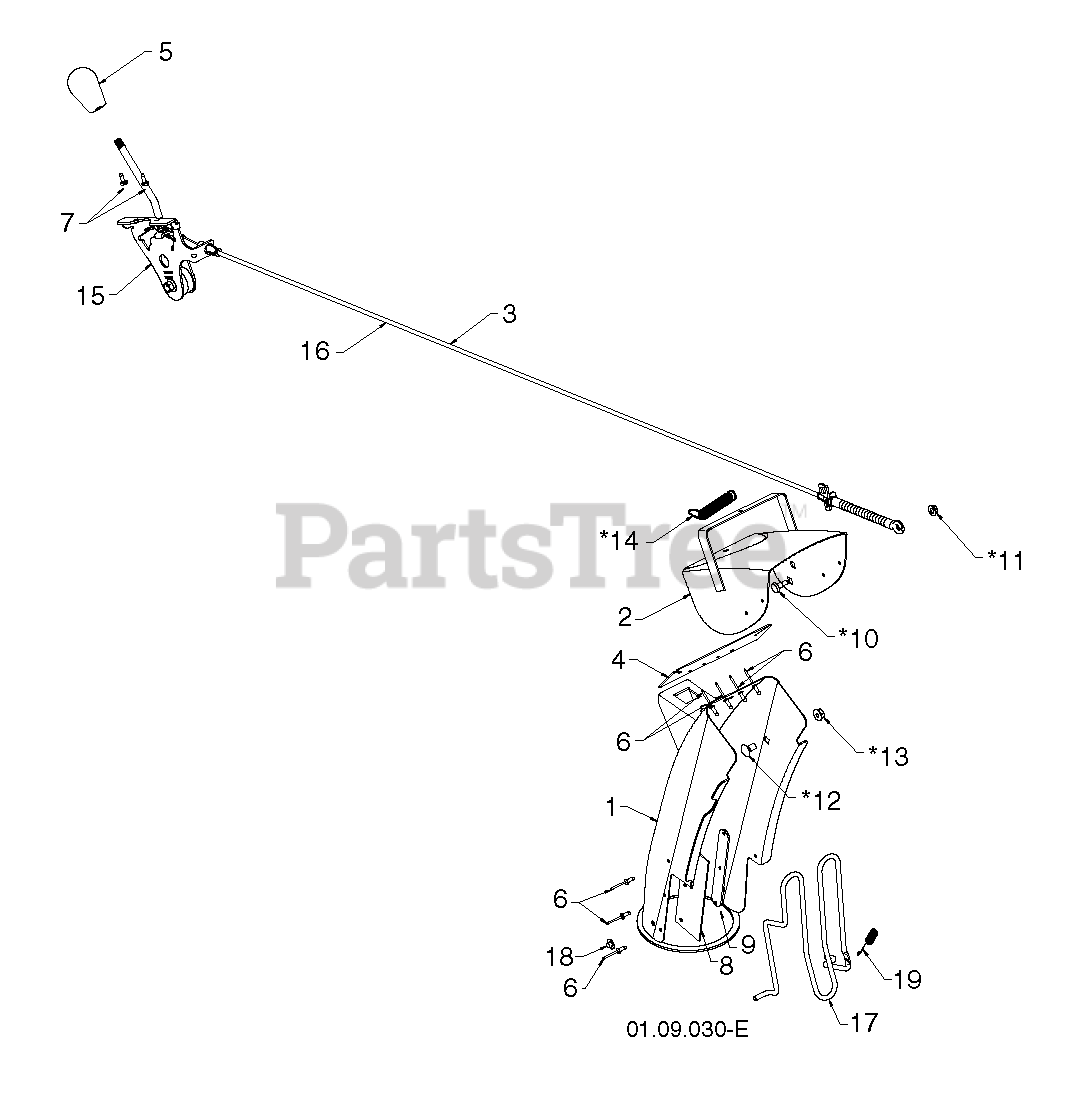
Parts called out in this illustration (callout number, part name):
1	ASM.CHUTE/DEFLECTOR.668
3	RP CABLE.DEFLECTOR.CONTRL.BOWD
5	KNOB.OVERMOLD.DS.HUSQVARNA/BLK
10	BOLT, SHOULDER
11	NUT.HEX.FLANGE.1/4
12	BOLT CAR BLK 5/16-18 X 5/8
13	LOCKNUT-FLANGE 5/16-18
14	SPRING.DEFLECTOR.REM.CHUTE
15	RP CNTRL.HEAD.ASSEM.DEFLECTOR
16	RP CABLE.DEFLECTOR.BOWDEN
17	ROD.GUARD.CHUTE (2 2)
18	NUT
19	SPRING.CHUTE.GUARD
